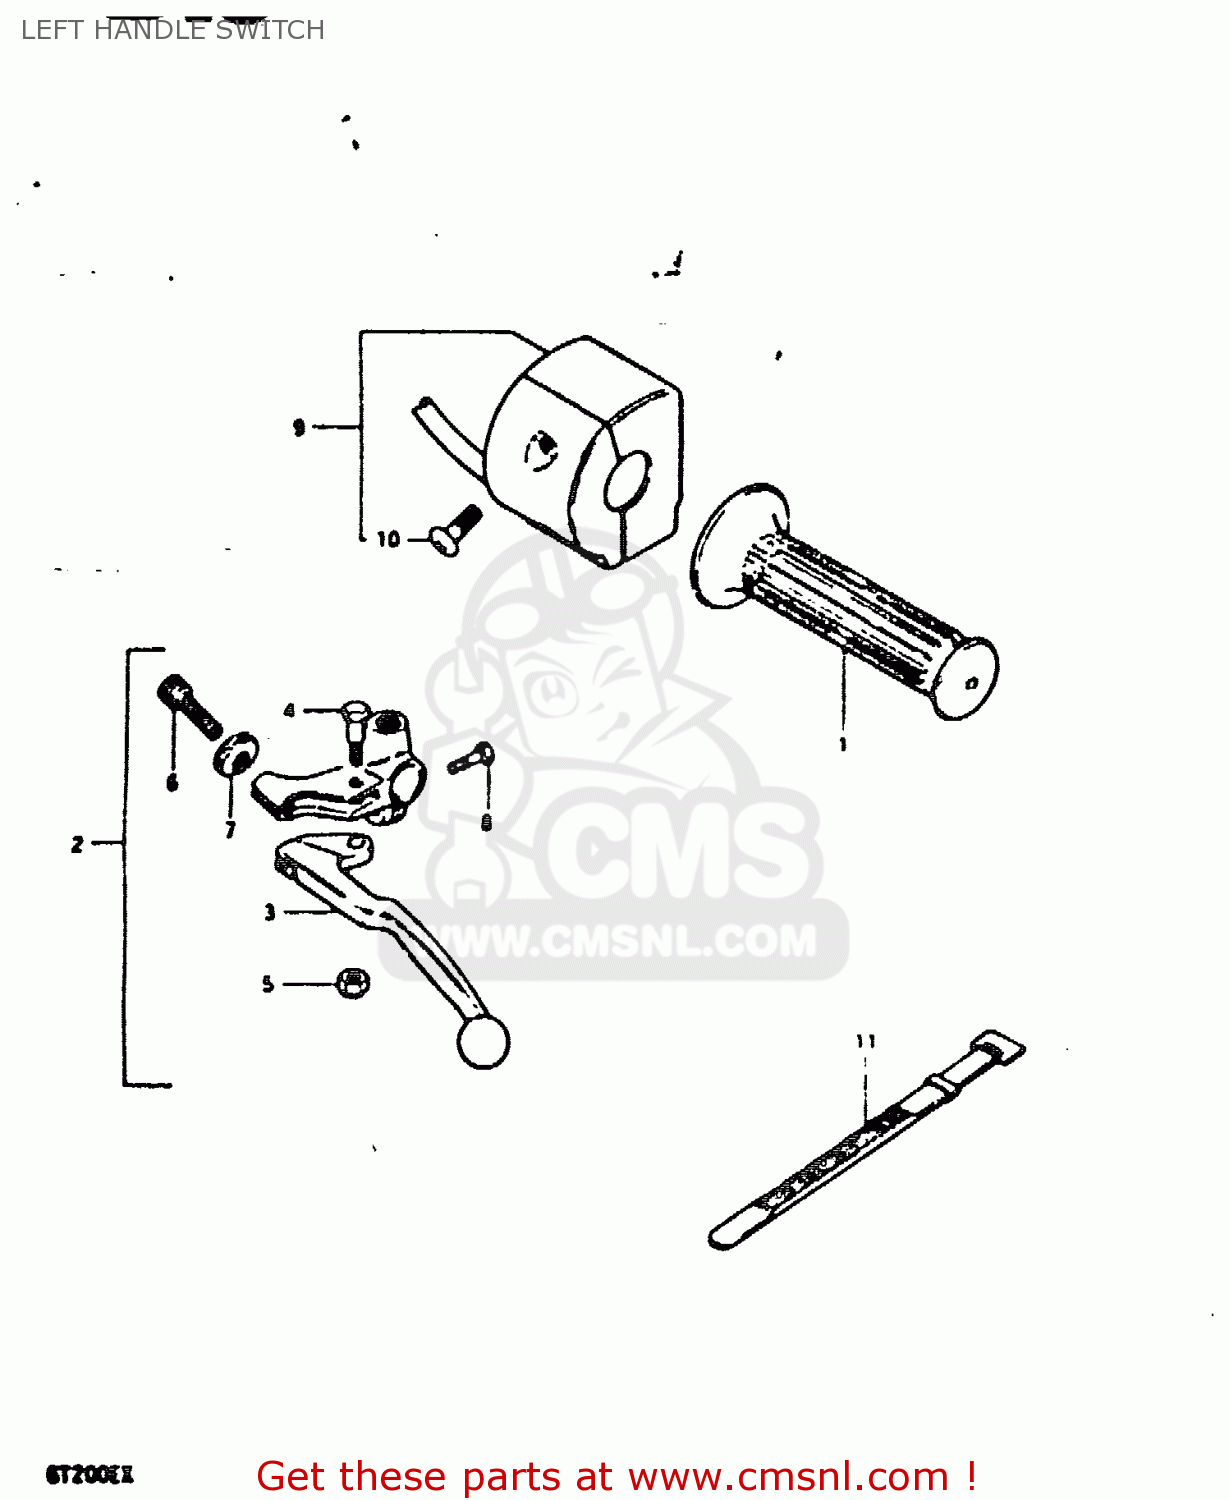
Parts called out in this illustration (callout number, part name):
1	GRIP,L
2	LEVER ASSY, CLUTCH
3	LEVER,CLUTCH
4	BOLT,LEVER
5	NUT 6MM
6	ADJUSTER,CABLE
7	NUT,CABLE ADJUSTER
8	BOLT
9	SWITCH ASSY, HANDLE LH
10	SCREW
11	CLAMP(L:120)
